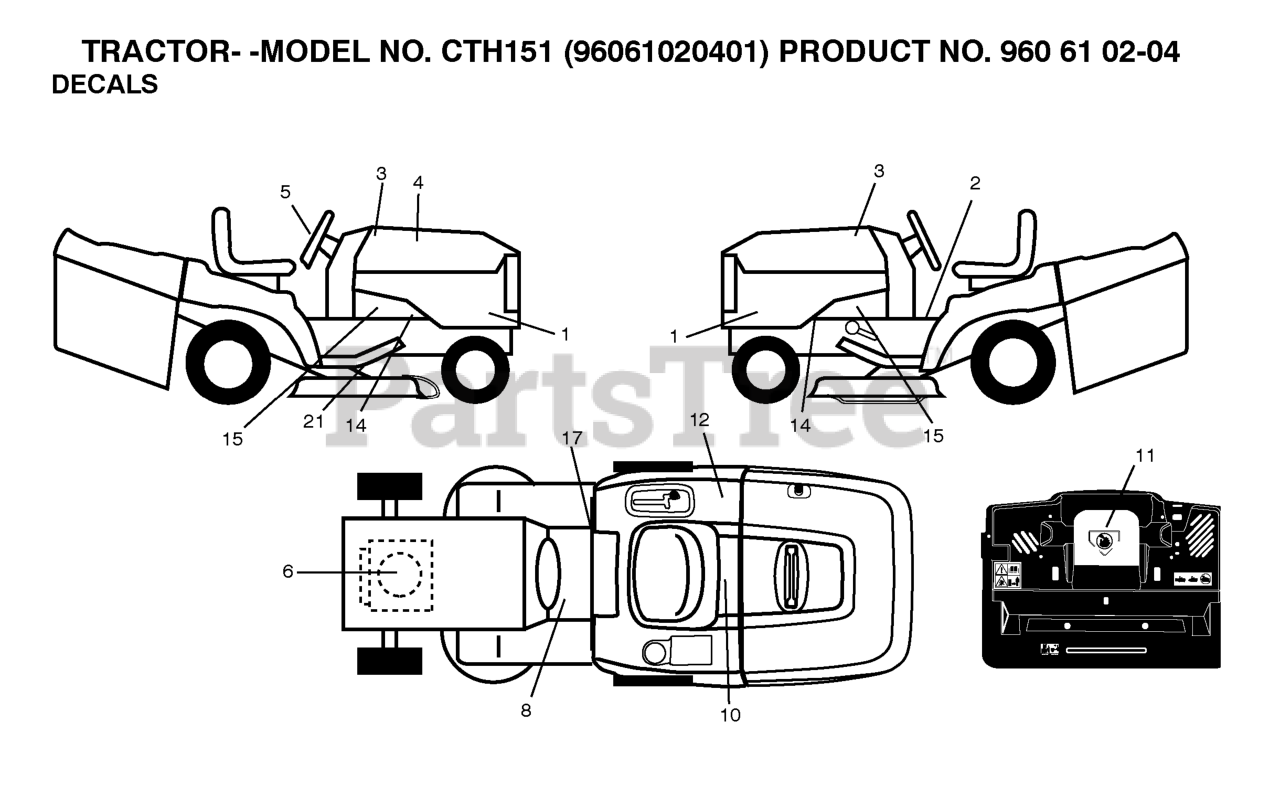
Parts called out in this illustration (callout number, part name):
1	DECAL PANEL
2	LABEL
3	DECAL.HOOD.NAMELOGO.HUSQ
5	DECAL.WHEEL.STRG.LGN.H
6	DECAL
8	DECAL
10	DECAL BTRY SYMBOLS
11	DECAL.INTERNATIONL.CUTFINGER
12	Decal, Fender 100 DB/CE
17	DECAL PARK BRAKE
